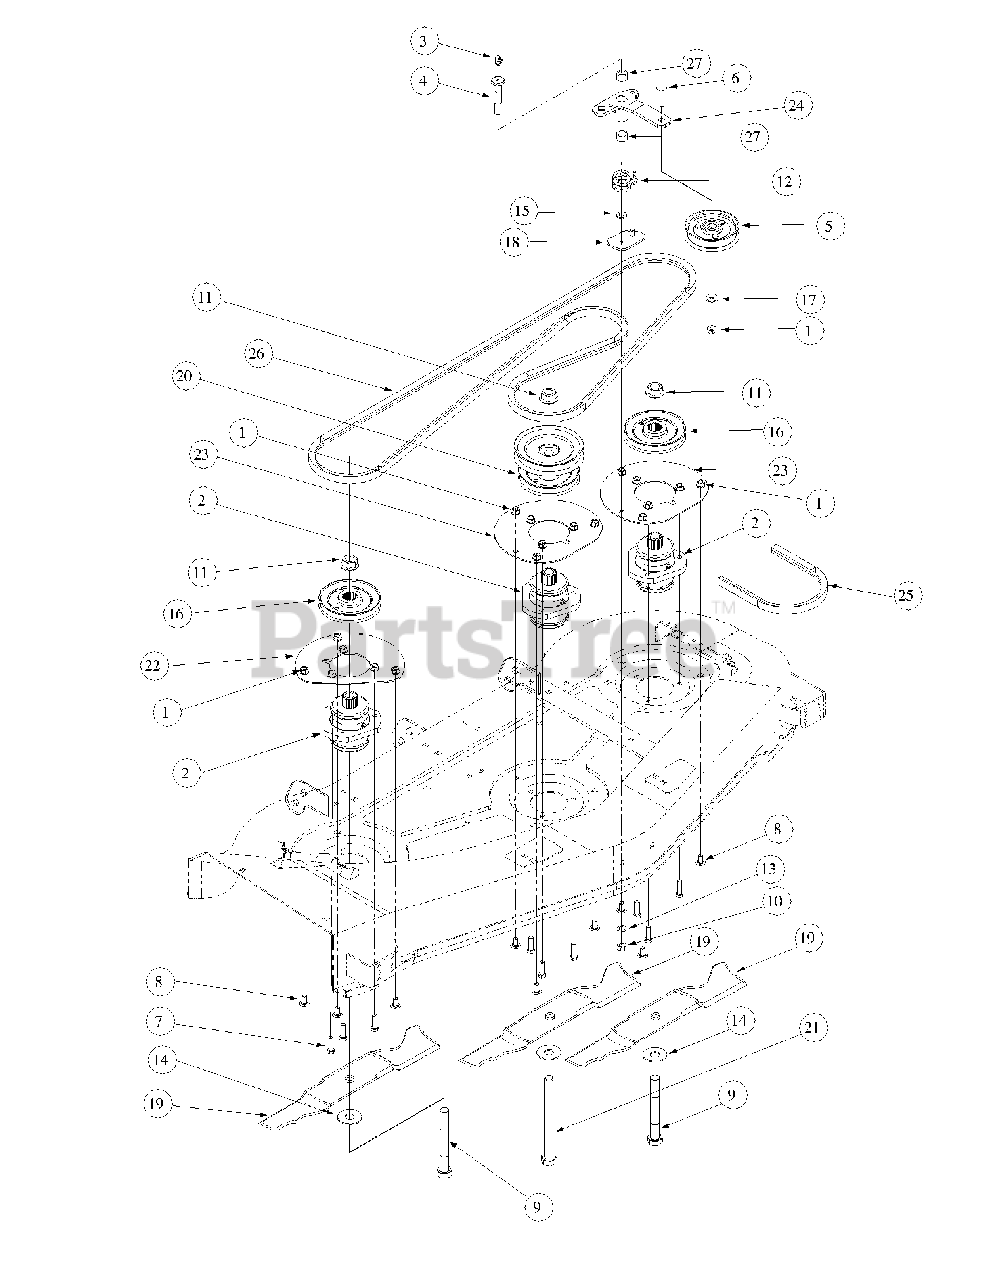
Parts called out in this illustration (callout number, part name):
1	Hex Nut 3/8-16 Flange Lock
2	Spindle Assembly w/Cups
3	Fit, 90 Tapper Grease 1/4-28
4	Shoulder Screw, 7/16-14
5	Idler Pulley Assembly, 4.00"
6	Screw, 3/8-16, 1.75, Hex Carrier
7	HHCS, 3/8-16, 1.25
8	Carrige Bolt, 3/8-16 x .75 LG.
9	HHCS, 3/4-16, 6.00
10	Hex Nut, 7/16-14
11	Flange Hex Nut, 3/4-16
12	Spring Idler Torsion
13	Lock Washer, 7/16
14	Flange Washer, .781 ID: 2.00 OD:.105
15	Flange Washer, .469 ID: .875 OD:.105
16	Pulley-V, 4.65 P.D.
17	Flange Washer, .406 ID: 1.0 OD: .105
18	Plate Idler Assembly
19	Blade, High Lift, 18.5 LG
20	Double Pulley
21	HHCS, 3/4-16, 8.00
22	Cover Plate, Right Hand
23	Cover Plate
24	Idler Arm Assembly, w/Briggs
25	Belt Drive, B Sect x 65.04 EL
26	Belt Spindle, A Sect x 122.0
27	Bearing Sleeve
